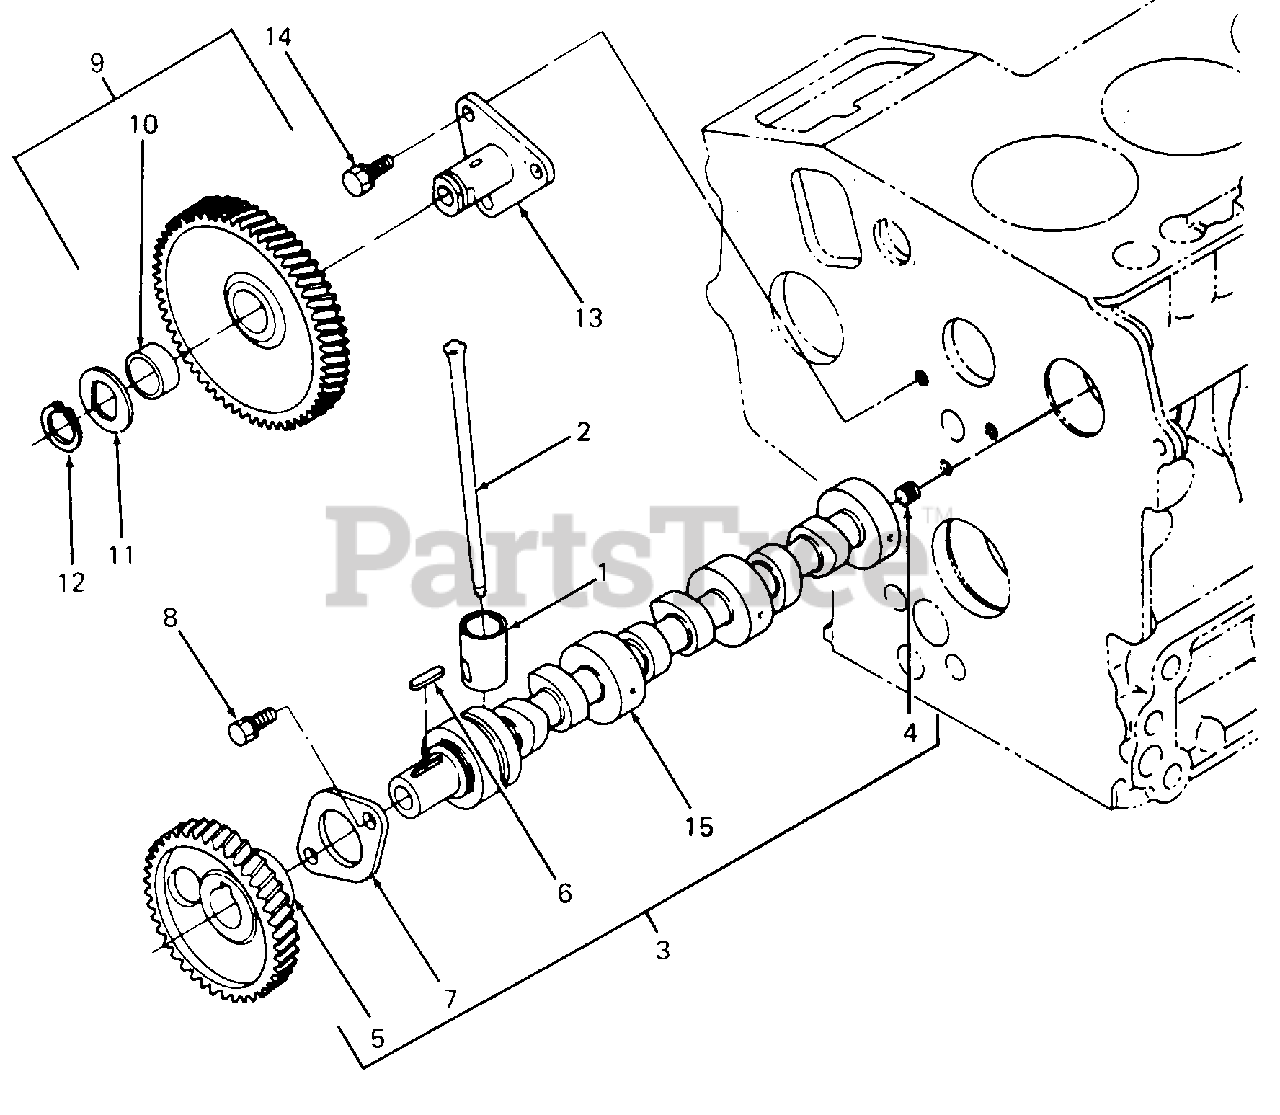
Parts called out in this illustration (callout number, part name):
3	Camshaft w/Gear
5	Gear, Camshaft
7	Stopper, Camshaft
8	Screw, Hex Cap w/Washer
9	Gear Assy, Idler
11	Collar, Idler Gear
12	Ring, Retaining
13	Shaft, Idler Gear
14	Screw, Hex Cap w/Washer
